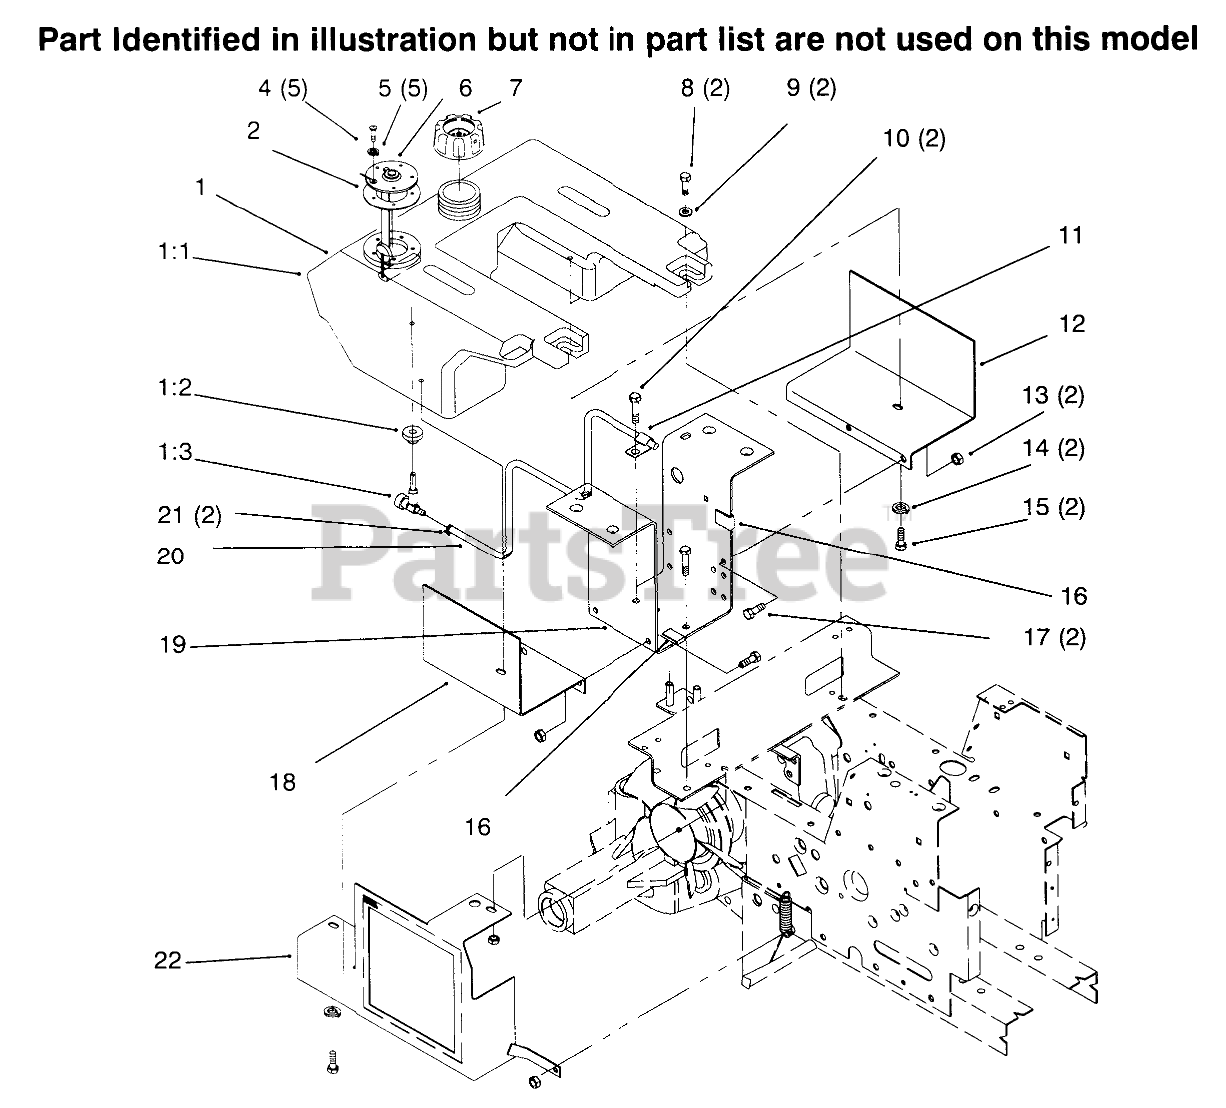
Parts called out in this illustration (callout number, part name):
1	TANK-FUEL
7	GAS CAP ASM
8	SCREW-HWHTF
9	WASHER-FLAT
10	SCREW-HH, LOCK
11	CLIP
12	Fuel Tank Support LH
13	NUT-LOCK, NI
14	WASHER-LOCK
15	SCREW-HH
16	CLIP-CABLE
17	SCREW-HH
18	Support-FueITank RH
19	Bracket-Fender
20	Line-Fuel 62"
21	CLAMP-HOSE
